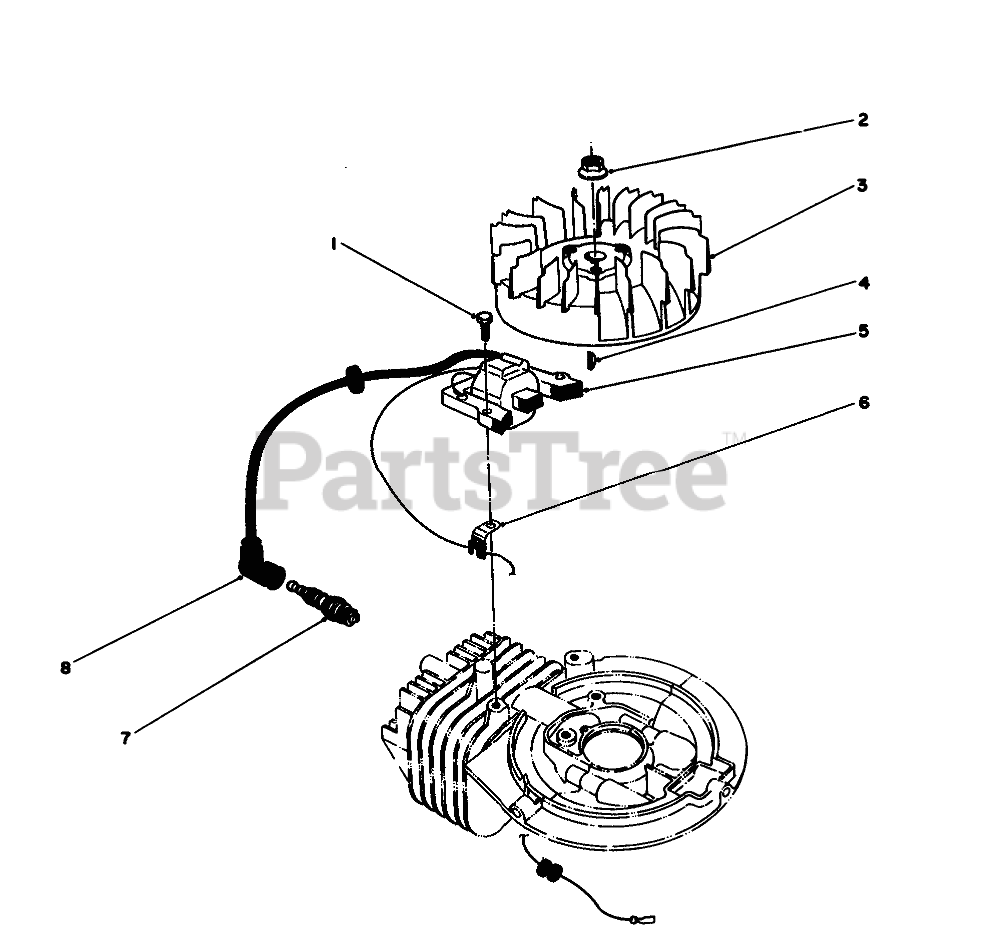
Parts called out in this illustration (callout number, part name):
1	SCREW
3	FLYWHEEL
5	COIL-MAGNETO
6	CLAMP
7	Sparkplug
8	CAP-SPARKPLUG
